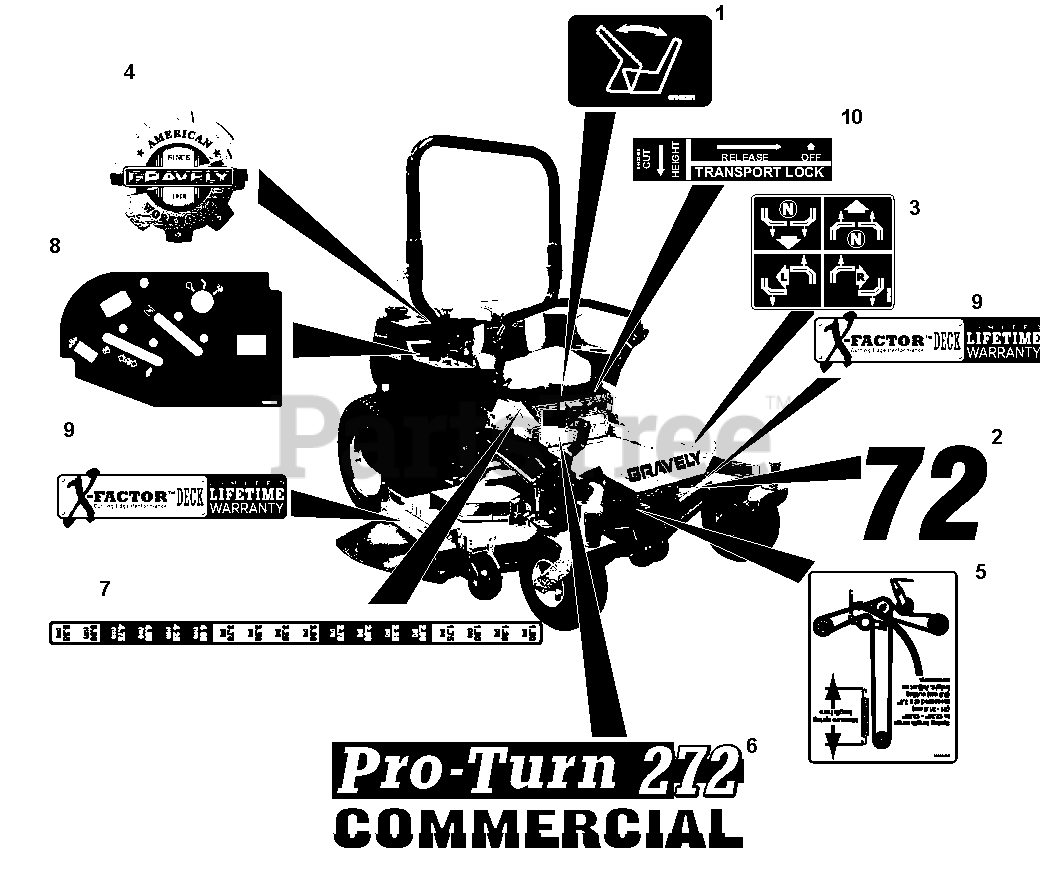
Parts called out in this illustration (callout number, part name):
1	Decal, Seat Release
2	Decal, 72
3	Decal, Instructional- Steering
4	Decal, Gravely Heritage, Large
5	Decal, Belt Routing
6	Decal, Pro-Turn 272
7	Decal, Height of Cut
8	Decal, Control Panel
9	Decal, X-Factor Deck
10	Decal, Transport Lock Instruction
